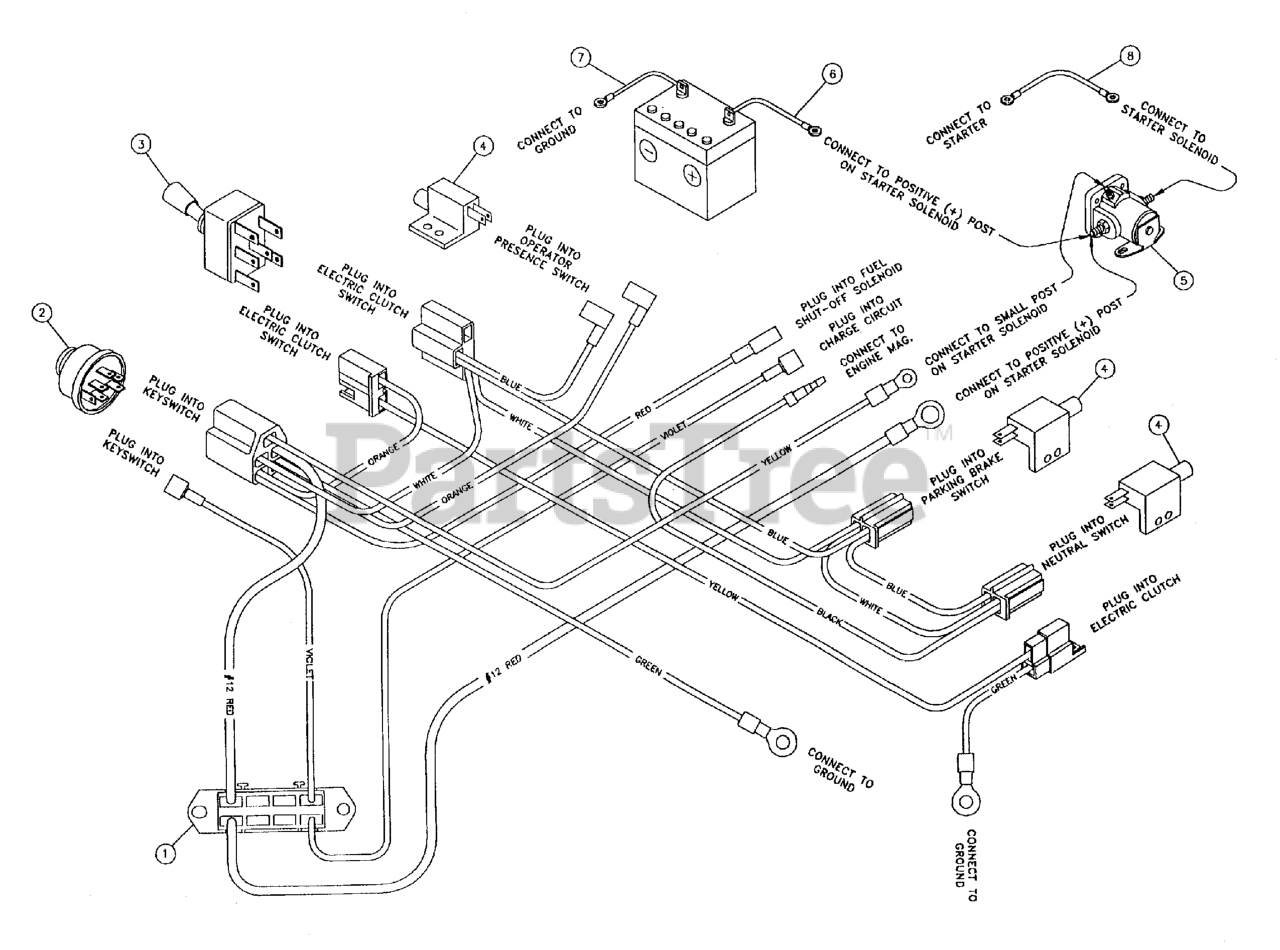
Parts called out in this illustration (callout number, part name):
1	DDSKAV23 Wire Harness
2	SWITCH, IGNITION, 6 POST
3	SWITCH, Electric Clutch
3	SWITCH, BLADE ENGAGEMENT
4	OPERATOR PRESENCE SWITCH = 5021769 (S/N: 1123 & UP)
4	PARKING BRAKE SWITCH = 5022095 (S/N: 3584 & ABOVE)
4	NEUTRAL SWITCH = 5022095 (S/N: 3584 & ABOVE)
5	SOLENOID, Starter
6	POSITIVE (+) BATTERY CABLE, 30"
7	BATTERY CABLE, NEG, 22, 1/4-5/16
8	POSITIVE (+) BATTERY CABLE, 22"
